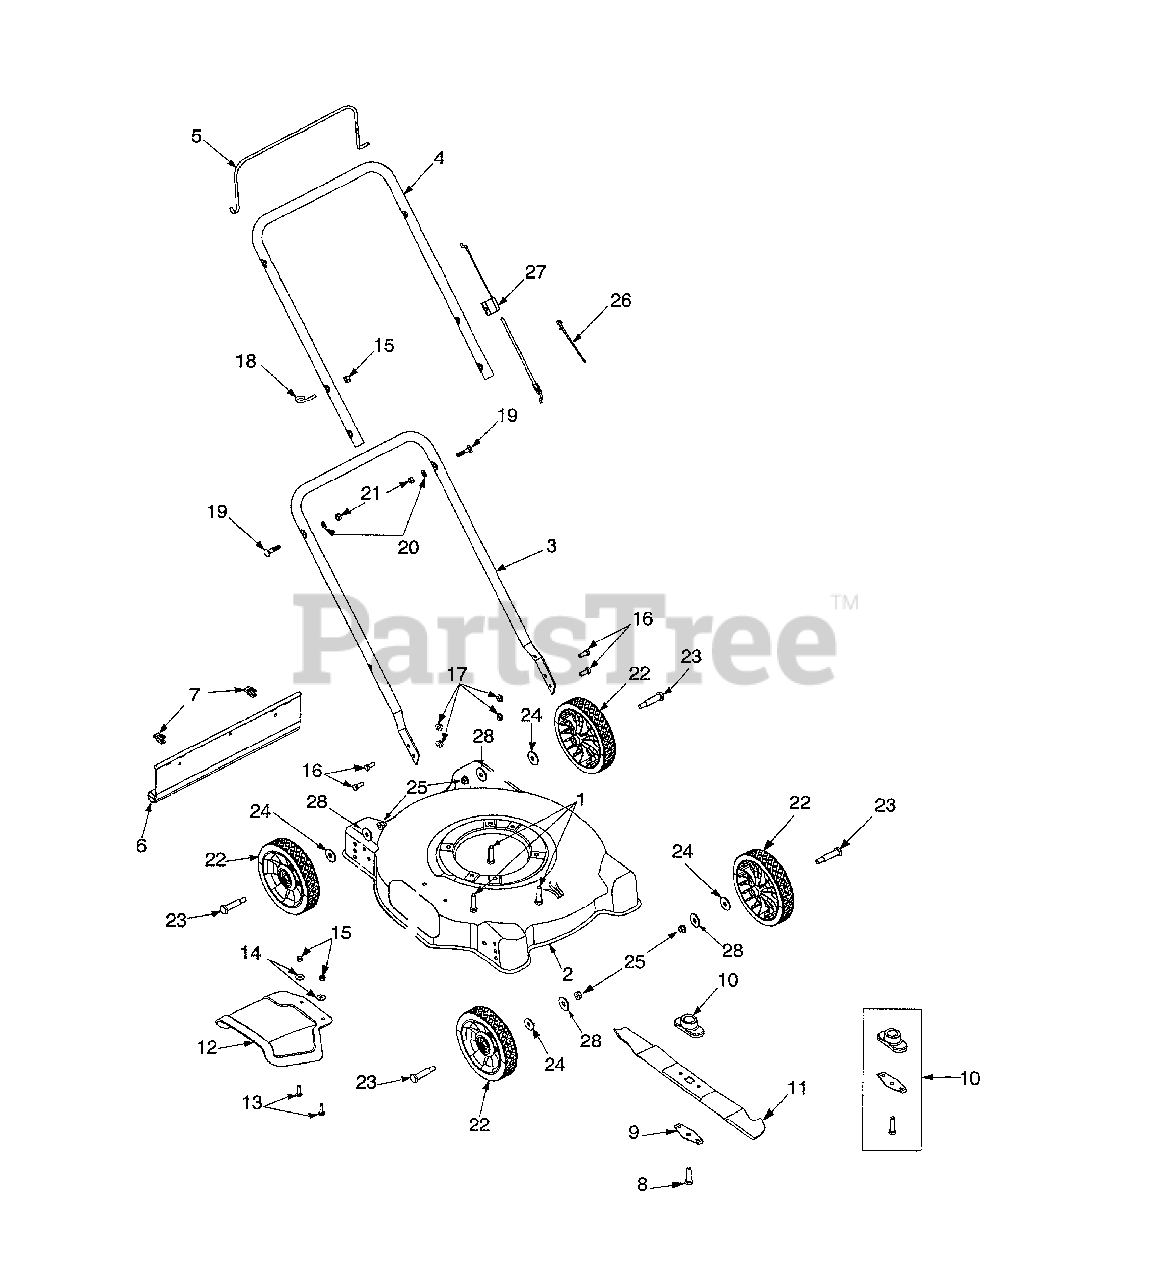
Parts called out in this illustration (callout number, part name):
1	Hex Ind. Washer Screw 3/8-16 x 1.0
6	Rear Flap
7	Hinge Clip
8	Screw 3/8-24 x 1.5" Group 8
9	Blade Bell Support
10	Blade Adapter Kit
11	Cutting Blade
12	Discharge Chute
13	Carriage Screw 1/4-20 x 1.0"
14	Flat Washer
15	Lock Nut 1/4-20
16	Hex Bolt 5/16-18
17	Lock Nut 5/16-18
18	Eye Bolt
19	Carriage Bolt 5/16-18 x 1.5"
20	Lock Washer
21	Nut 5/16-18
22	Wheel
23	Shoulder Screw .498 x 1.635
24	Bell Washer
25	Flange Lock Nut
26	Cable Tie
27	Control Cable (48.25" Ig.)
28	Bell Washer
